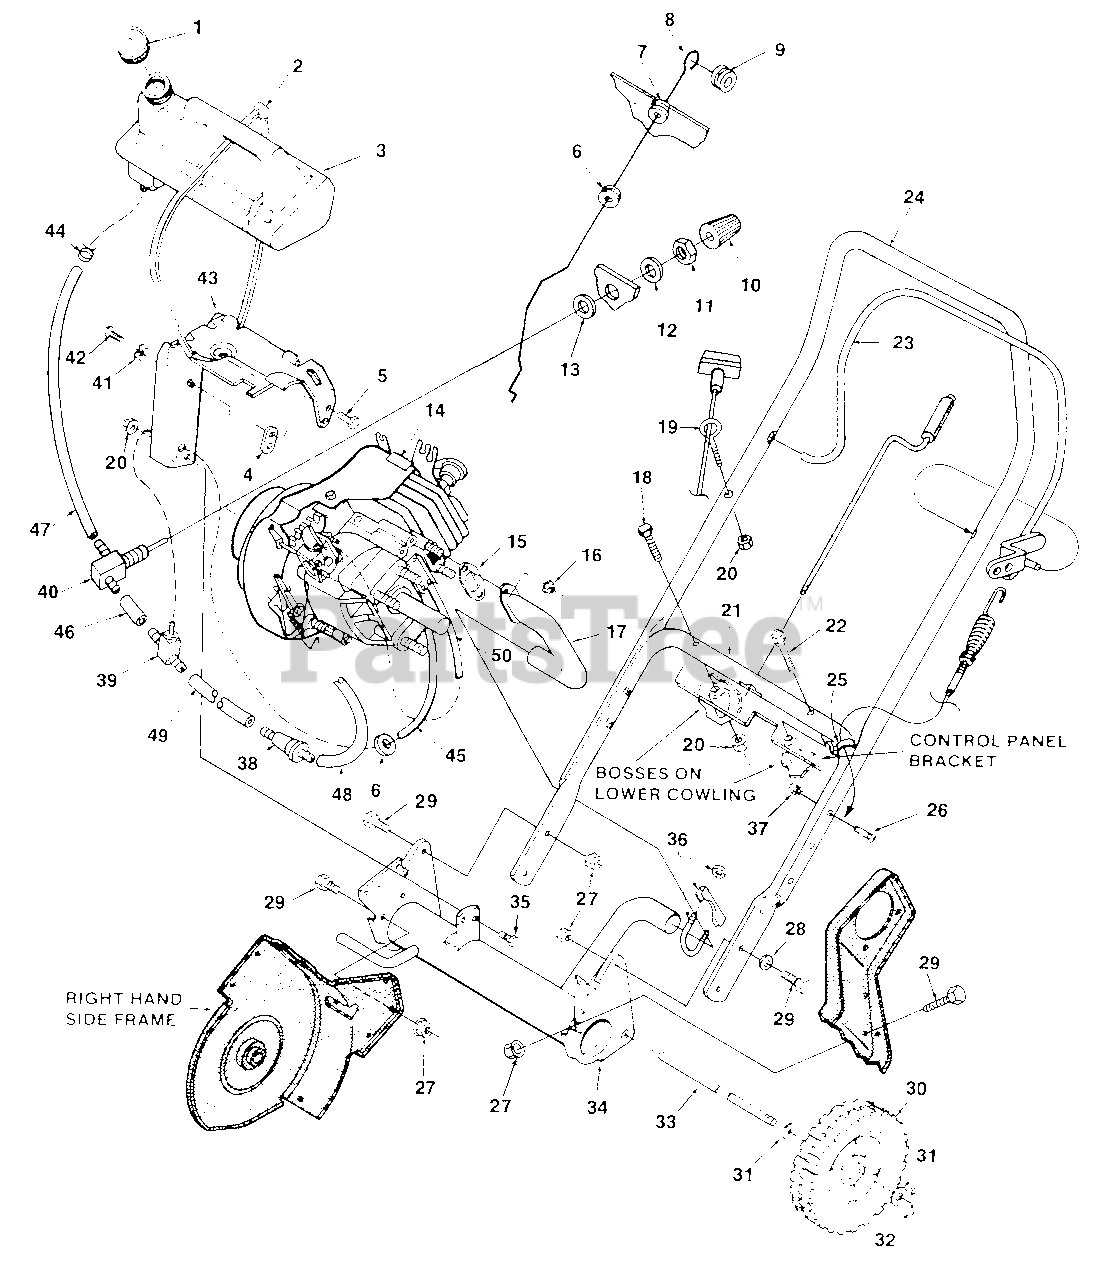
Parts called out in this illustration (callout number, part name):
2	TIE-Strap
3	TANK-Fuel
4	SPACER
5	SCREW-Thd. forming #10-24 x 3/4
8	ROD-Choke
10	KNOB-Shut-Off
11	NUT-Hex 7/16-20
12	WASHER-Lock 7/16
13	WASHER-Flat 7/16
14	SHORT BLOCK
15	GASKET-Manifold
16	NUT-Hex 5/16-18
17	MANIFOLD- Exhaust
18	SCREW-Hex hd. Cap 1/4-20 x 1 1/2
20	NUT-Flange 1/4-20
21	HANDLE-Lower
22	SCREW-Hex washer #10-16 x 1 1/2
24	HANDLE-Upper
25	TIE-Cable
26	SCREW- Phil. Pan Hd. 1/4-20 x 1 1/2
27	NUT-Flange 5/16-18
28	WASHER-Flat 5/16
29	SCREW-Hex 5/16-18 x 5/8
30	WHEEL & TIRE
31	WASHER-Flat 13/32
32	PIN-Cotter 3/32 x 3/4"
33	SHAFT-Axle
35	SCREW-Hex 1/4-20 x 1/2
36	CLAMP- Muffler
38	FILTER-Fuel
39	FITTING-Fuel
41	WASHER-Lock 1/4"
42	BOLT- Hex 1/4-20 x 3/8
43	BRACKET-Fuel tank
45	TUBE-Rubber 17"
46	TUBE-Rubber (cut to 1 1/2")
47	TUBE-Rubber (cut to 7 1/4")
48	TUBE-Rubber (cut to 8")
49	TUBE-Rubber (cut to 13 1/2")
50	TUBE-Rubber (cut to 10 1/4")
